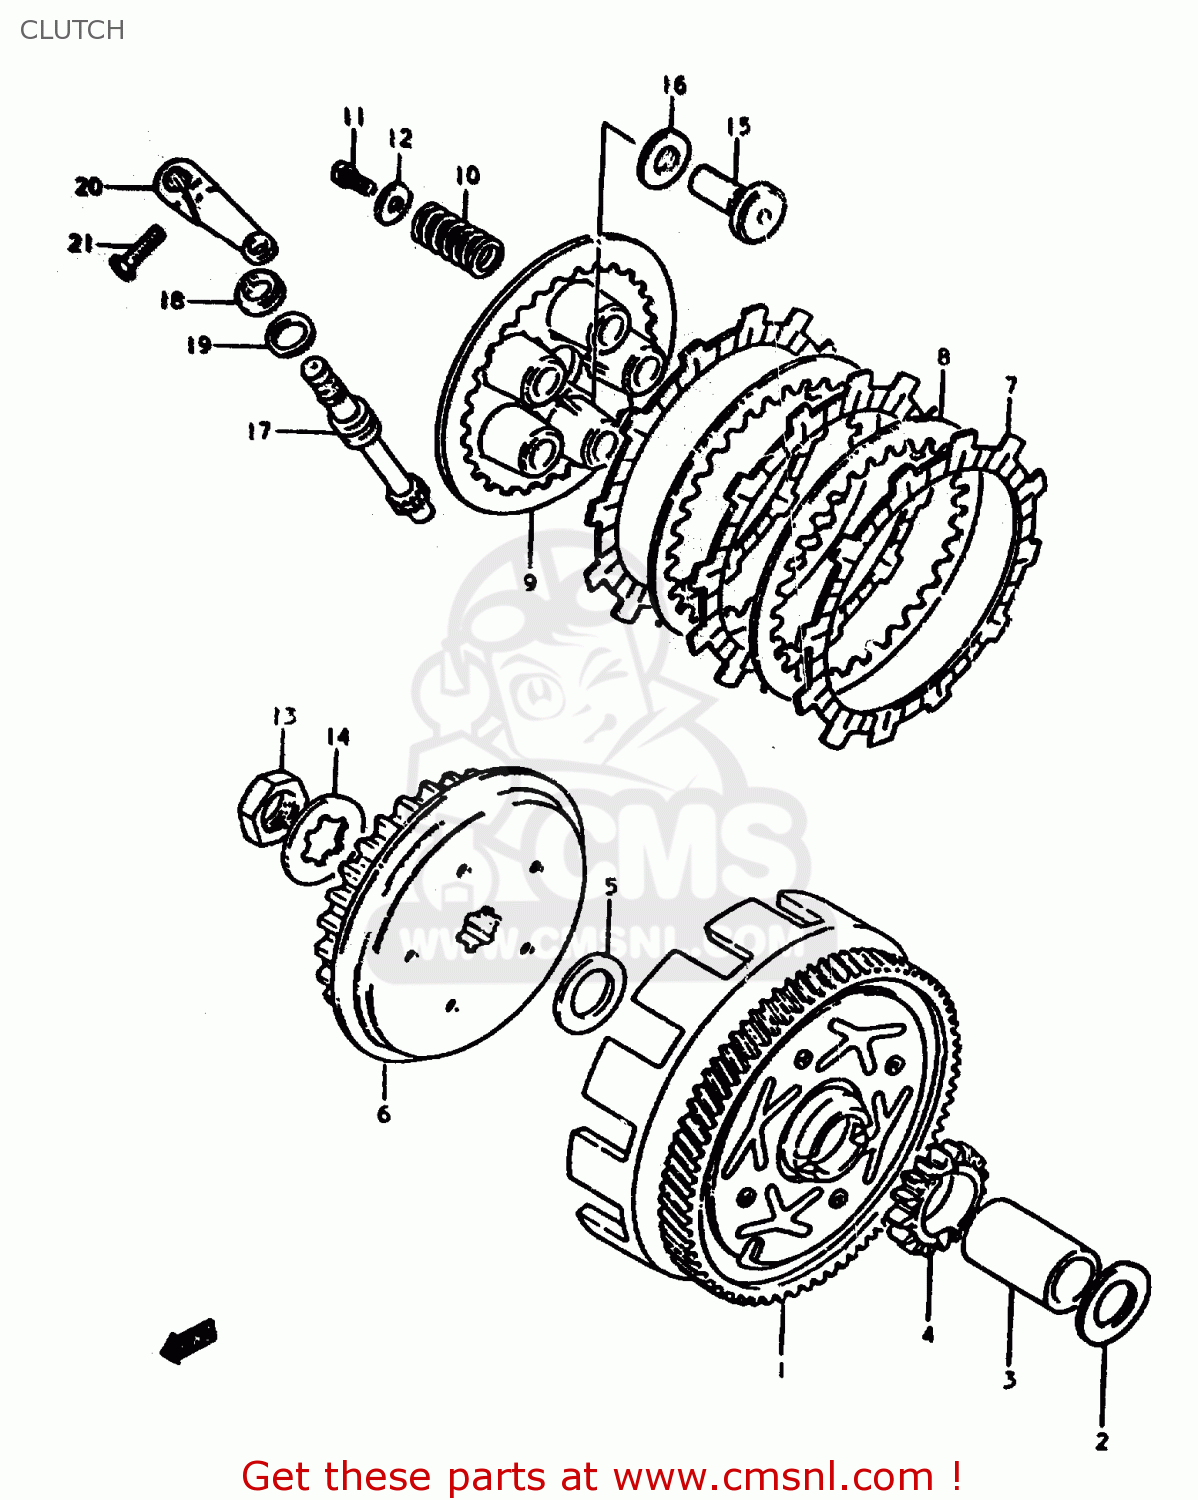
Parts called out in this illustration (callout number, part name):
1	GEAR ASSEMBLY,PRIMARY DRIVE
2	WASHER,THRUST
3	SPACER
4	GEAR,KICK STARTER DRIVE
5	WASHER
6	HUB,CLUTCH SLEEVE
7	PLATE,CLUTCH DRIVE
8	PLATE,CLUTCH DRIVEN (NAS)
9	DISC,CLUTCH PRESSURE
10	SPRING
11	BOLT(5X16)
12	WASHER (5.5X16X1.2)
13	NUT
14	WASHER,LOCK
15	RACK,CLUTCH RELEASE
16	BEARING(10X22X2.8)
17	PINION,CLUTCH RELEASE
18	OIL SEAL
19	WASHER (12X17X1)
20	ARM,CLUTCH RELEASE
21	BOLT, UPPER
